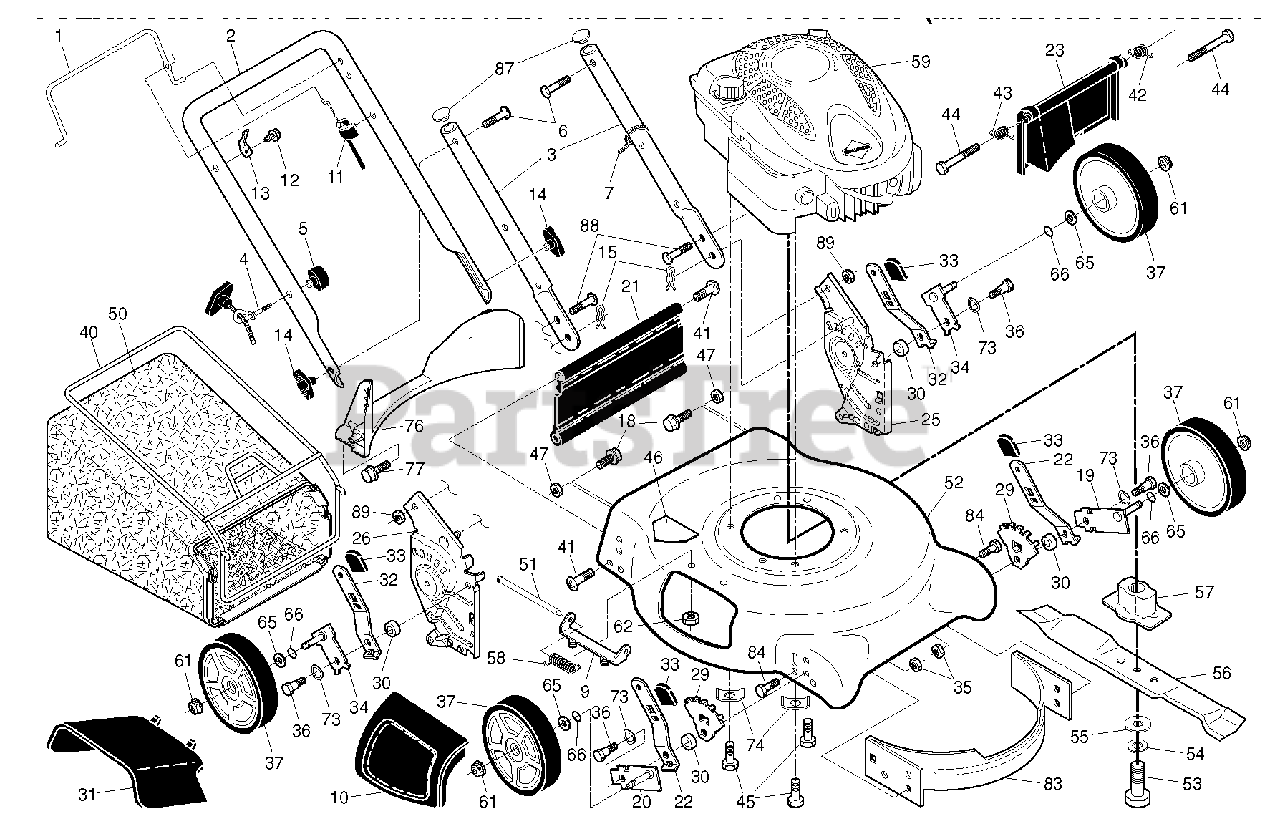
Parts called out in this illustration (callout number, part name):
1	BAIL.CONT.D.STRAIGHT.PUSH.YELL
2	HANDLE.UPPER.ECONOMY.BLACK
3	HANDLE.LOWER.DOME.BT.BLACK
4	Rope Guide, Blk Zinc Chrom
5	T-KNOB.NEW ROPE GUIDE
6	BOLT, HANDLE 5/16-18X1.75
7	TIE GUIDE
9	BRACKET.ASM.HOUSING.EZ.MUL
10	MULCH DOOR
11	CABLE.MZR.RATO.22"LOW.
13	BRACKET.UPSTOP.RT
15	HAIRPIN COTTER
18	SCREW 1/4X20
19	AXLE ARM ASSY FRONT LH
20	AXLE ARM ASSY FRONT RH
21	KIT.SKIRT.21 DOMED.W/LIP
22	SELECTOR SPRING, FRONT
23	REAR DOOR ASSY
25	BRACKET.ASM.HAND.LW.21.LT.BLAC
26	BRACKET.ASM.HAND.LW.21.RT.BLAC
29	WHEEL ADJ BRACKET FRONT
30	SPACER.HEIGHT.ADJUSTER
31	CLIP ON DISCHARGE GUARD
32	SPRING.SELECTOR.21RD.HTTRT.BZP
33	KNOB.ERGO.DLX.PLAS.MARI.MULTI
34	ARM.ASM.AXLE.REAR.5/9.POS.BZP
35	NUT.FLANGE.HEX.5/16X18.BLACK
36	SHOULDER BOLT 5/16-18
37	WHEEL.12X1.75.5SPK.RAD3.BLACK
40	FRAME.BAG.21.REAR.DOMED.PUSH
41	SCREW.1/4-20X21/4.HEX.
42	SPRING.LH.22.REAR.DOOR.EZ.EMPT
43	SPRING.RH.22.REAR.DOOR.EZ.
45	BOLT 3/8-16X1-1/8
46	No Step Decal
47	NUT.71038.31-18.HEX.NYLOCK
50	GBAG.27510416S.BLK.PPR
51	ROD.HINGE.COMBI-C
52	HOUSING.21".MC.PUSH.YELLOW.E/F
53	SCREW, HEX HD 3/8-24 X 1-3/8
55	WASHER,HARDEN
56	BLADE.21.PUSH/RWGD/FWGD
57	ADAPTER.BLADE.W/KEY.25MM.CE
58	TORSION SPRING
61	NUT.HEX.FLANGE.3/8-16.LOCKNUT
62	LOCKNUT.NYLOC.1/4-20
65	WASHER PM
66	O-RING..070X.487.NEOPRENE
73	WASHER.CURVED.CYLINDRICAL
74	WASHER.ENGINE.BZP
76	BAFFLE.REAR.PLASTIC.21.RD.ECON
77	SCREW.HX.13X.750
83	BAFFLE.FRONT.21.DOME.US
84	BOLT.5/16HEX.WHS.HD
87	PLUG.PLASTIC.7/8".14-20.GAUGE
89	LOCKNUT-FLANGE 5/16-18
